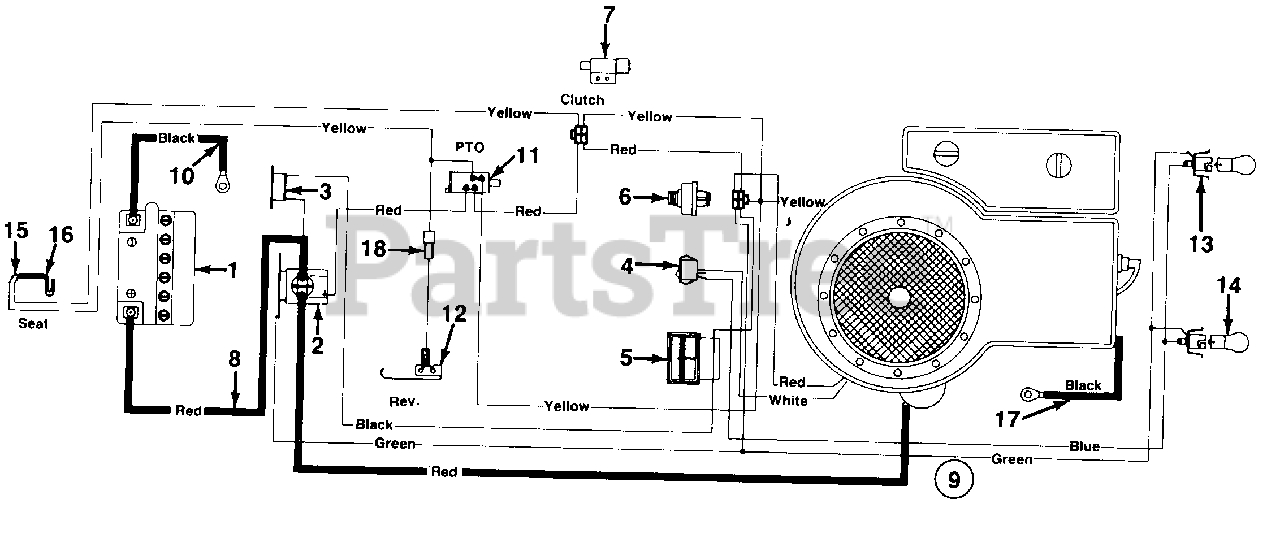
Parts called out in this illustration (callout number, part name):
1	Battery
2	Solenoid
3	Circuit Breaker
4	Light Switch
5	Ammeter
6	Ignition Switch
7	Safety Switch (Clutch)
8	Electric Wire 8" Lg.
9	Wire Harness
10	Ground Wire 11.5" Lg.
11	Safety Switch (Deck)
12	Safety Switch (Reverse)
13	Socket
14	Bulb
15	Safety Switch (Seat)
16	Safety Switch (Seat)
17	Ground Wire 7.5" Lg.
18	Ext. Wire
